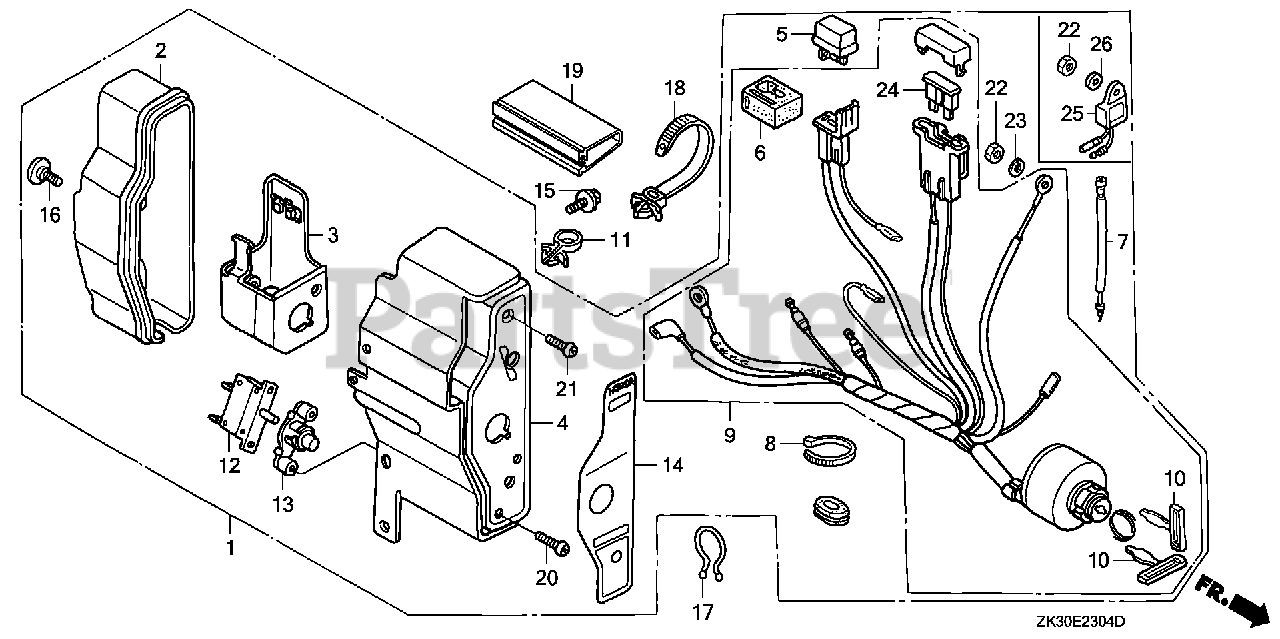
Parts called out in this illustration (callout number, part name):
1	BOX ASSY., CONTROL (3A) *NH1* (ALERT) (BLACK)
1	BOX ASSY., CONTROL (3A) *R280* (EXP-ALERT) (POWER RED)
2	CASE, CONTROL
3	BRACKET, CASE MOUNTING
4	PANEL, CONTROL *R8* (BRIGHT RED)
4	PANEL, CONTROL *R280* (POWER RED)
5	RECTIFIER ASSY., SILICON (SHINDENGEN)
6	SUSPENSION, CONNECTOR
7	SUB-WIRE HARNESS
9	SWITCH ASSY., COMBINATION (3A-CHARGE)
10	KEY (HONDALOCK)
11	HOLDER, STOP SWITCH WIRE
12	PROTECTOR, CIRCUIT (3.5A)
13	LENS ASSY., PROTECTOR
14	MARK, CONTROL BOX (EXP)
15	BOLT, FLANGE (6X12) (CT200)
16	SCREW, SPECIAL (6X12)
17	CLIP, PURSE LOCK
18	STRAP, CABLE (118MM) (BLACK)
19	TUBE, FASTENER (30MM)
20	SCREW, PAN (3X12)
21	SCREW, PAN (4X12)
22	NUT, HEX. (4MM)
23	WASHER, SPRING (4MM)
24	FUSE, BLADE (15A)
25	ALERT UNIT, OIL
26	WASHER, PLAIN (4MM)
